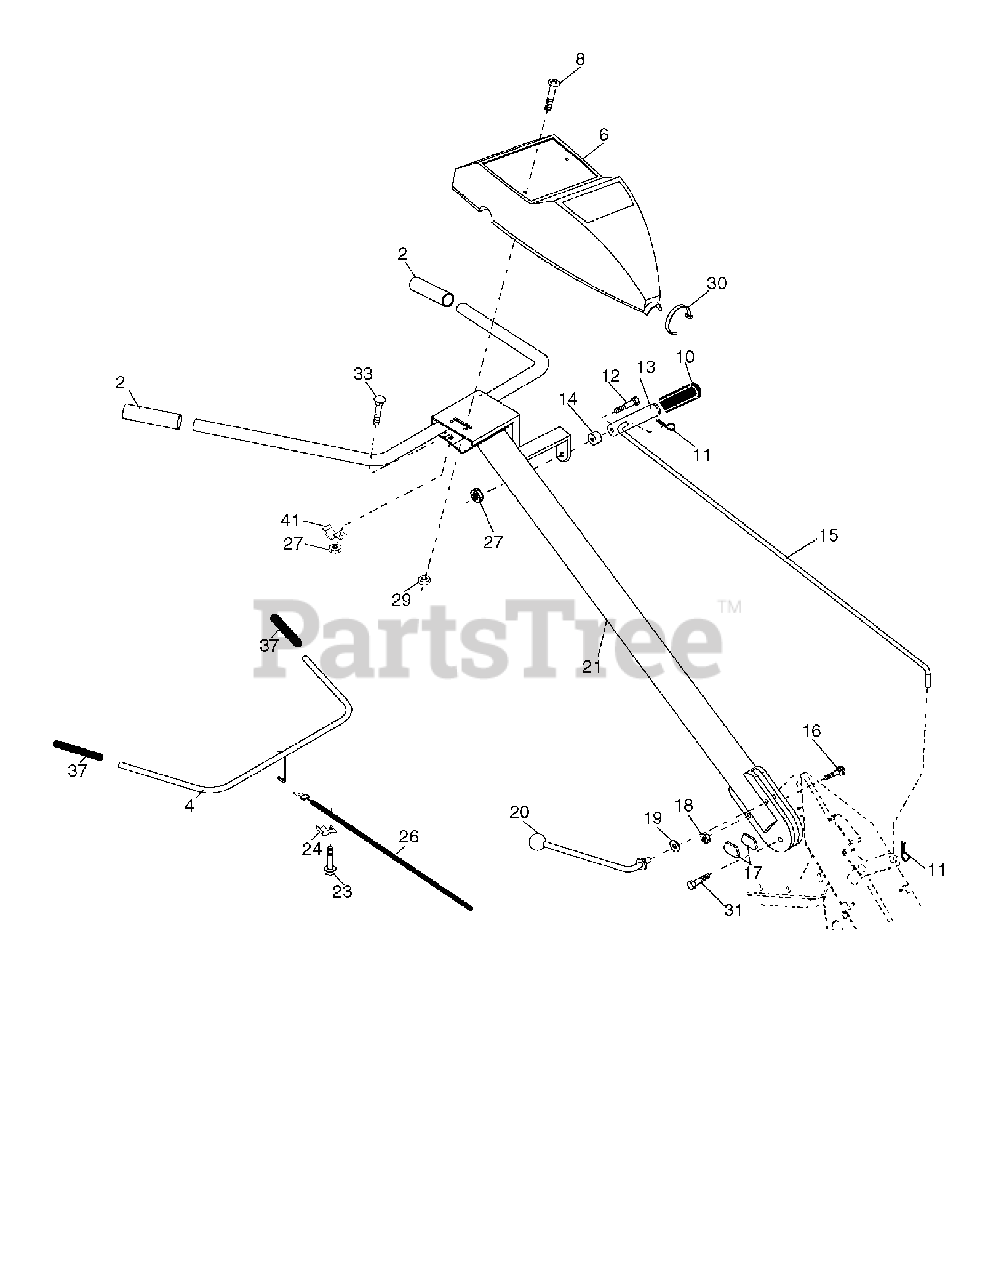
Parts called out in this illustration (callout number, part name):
2	GRIP.1X5.06
4	CONTROL BAR ASSY
6	PANEL.CONTROL.BLACK.NO.SLOT
8	SCREW.PNHD.10-24
10	GRIP T
12	SHOULDER BOLT ST
13	HANDLE.SHIFT.TILLER
14	GROMMET.RUBBER.CRT.TILLER
15	SHIFT ROD CRT
17	LOCK.HANDLE.CRT
18	LOCKNUT
19	WASHER CRT
20	LEVER.LOCK.CRT
21	HANDLE.ASM.GREY
24	CONDUIT CLIP T
26	CABLE.CLUTCH
27	NUT T
29	NUT **
30	TIE CABLE CRT
31	BOLT.PIVOT
37	GRIP BAR CRT(1)
41	CLAMP.BAR.CRT.BLACK
